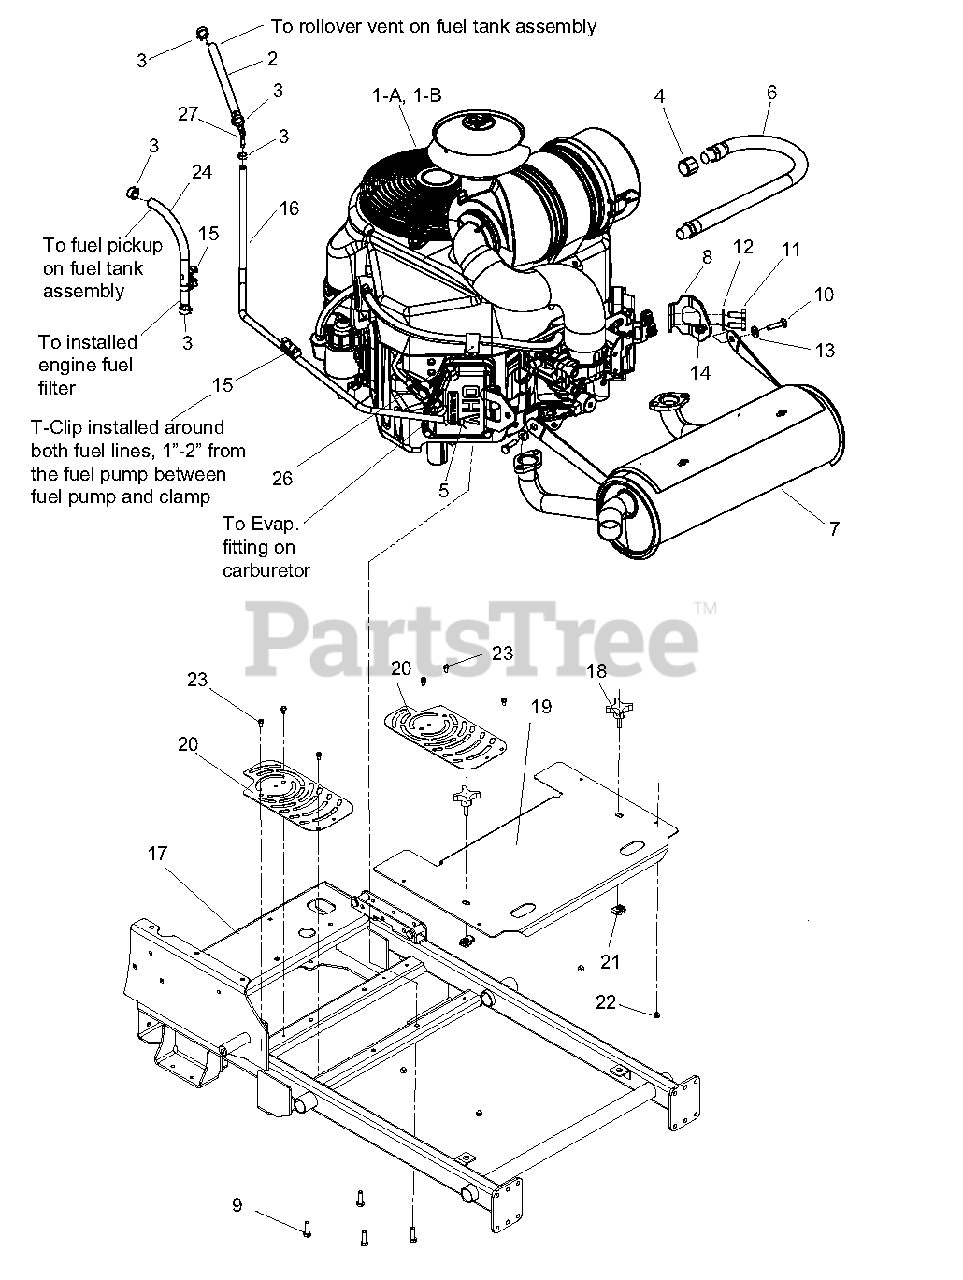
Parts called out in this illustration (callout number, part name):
1-A	ENGINE, KAWASAKI FX 170 (994114)
1-B	ENGINE, KAWASAKI FX691 (994111,112,117,118)
2	HOSE, .25 LOW-PERM BULK GAS (5")
3	CLAMP, FUEL LINE
4	PIPE CAP 3/8 NPT FEMALE
5	CLAMP - HOSE, SPRING .188
6	DRAIN , M20 OIL
7	EXHAUST, KAWASAKI PROSTANCE
8	BRKT, EXHAUST
9	BLT-HEX .38-16 X 1.25 FTH GR5 YZ EP80
10	BLT-HEX .25-20 X 1.00 GR5 YWZC
11	BLT-HEX M8-1.25 X 20 YWZC
12	WSHR-LK .31 X .078 REG YWZC
13	WSHR-FL-STL .281 X .62 X .065 YWZC
14	NUT-LK-NYL-FLG .25-20 YWZC
15	CLIP, 7 .38-50
16	HOSE, .188 LOW=PERM BULK GAS (33")
17	WLDMT, FRAME PROSTANCE
18	KNOB, 3/8 X 1.25 - 4 PRONG
19	SHIELD, DECK
20	GUARD, FAN
21	NUT, RTNR .375-16 X .37
22	BUMPER GROMMET .125 X .25 REV
23	SCR TAP .25-20 X .50 HWH TR YWZ
24	HOSE, .25 LOW-PERM BULK GAS (10") (994117,118)
25	CLAMP, FUEL LINE (994117,118)
26	CLAMP, INSULATED STEEL
27	FITTING, 90 VACUUM 3/16-1/4
